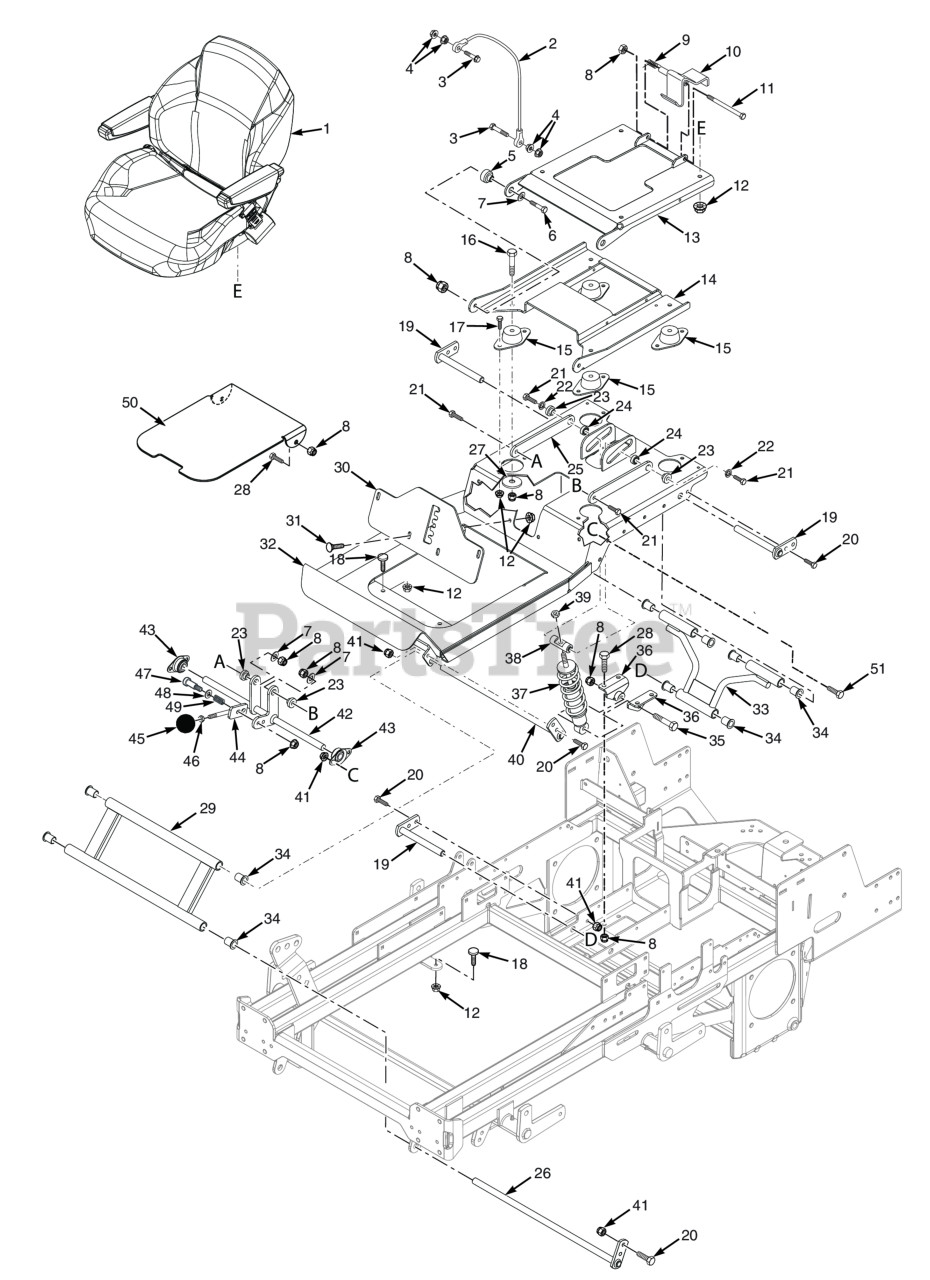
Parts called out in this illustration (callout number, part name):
1	Seat Assembly (INCL 14)
2	Cable, Seat Stop
3	SERR. FLG. HEX HEAD CAPSCREW, 5/16-18 X 3/4
4	NUT, 1/4-20 SERRATED FLANGE HEX HEAD
5	Sleeve, Seat Base Mounting
6	Capscrew, Hex Head 3/8-16 x 2.0"
7	Flatwasher, 3/8" Special (.391 x .938 x .105)
8	HEX NUT, ELASTIC STOP LOCK, 3/8-16
9	Spring, Seat Latch
10	Latch Weldment, Seat
11	Bolt, 3/8-16 x 6.00" Hex Head
12	Nut, Serrated Flange 5/16-18 (Right Front Engine Mounting, Briggs and Kohler Only)
13	Seat Plate Weldment
14	Seat Mounting Plate Weldment w/Decal
15	Isolator, Seat
16	Bolt, Hex Head 3/8-16 x 2-1/4" - 61"
17	BOLT, SERRATED FLANGE HEX HEAD 5/16-18 X 3/4"
18	Bumper, Rubber
19	Shaft Weldment, Rear Op. Platform Pivot
20	Bolt, Heax Head 5/16-18 x 1" (48V / 52V)
21	Bolt, Hex Head 3/8-16 x 1-1/2" B&S 32BV
22	Lockwasher, 3/8" Spring, Kawasaki FX / FT & FT-EFI / B&S 32BV
23	BUSHING, SPEED ADJUSTMENT LEVER
24	Bearing
25	Link, Suspension Seat Tensioner
26	Pin Weldment, Op Platform Lower Pivot
27	Flatwasher, 3/8-.406 x 2.25" x .1875
28	Bolt, Hex Head, 3/8-16 x 1 Gr. 5
29	Suspension Pivot Assembly, Front
30	Bracket, Suspension Adjustment w/Decal
31	Bolt, Carriage 5/16-18x1" (large frame units only)
32	Seat Mounting Base Weldment w/Decal
33	Suspension Pivot Assembly, Rear
34	Bearing, .625 ID Plastic
35	Capscrew, Hex Head 3/8-16 x 2.75"
36	Mount Weldment, Shock
37	Shock Absorber, Suspension
38	Mount, Suspension Shock
39	Nut, Elastic Stop 3/8-16, grade 8 black
40	Pin Weldment, Op Platform Upper Pivot
41	HEX NUT, ELASTIC STOP LOCK, 5/16-18
42	Pivot Weldment, Suspension Tensioner
43	Bearing, Self Aligning - 5/8 I.D.
44	Adjustment Lever, Suspension
45	Knob, OCDC Lever
46	Nut, Jam 3/8-16
47	Bolt, Shoulder 3/8 x 1"
48	Flatwasher, 3/8 (.406 x .812 x .065)
49	Spring, Speed Control Slide
50	Cover, Foot Plate
51	BOLT, SERRATED FLANGE HEX HEAD 5/16-18 X 3/4"
